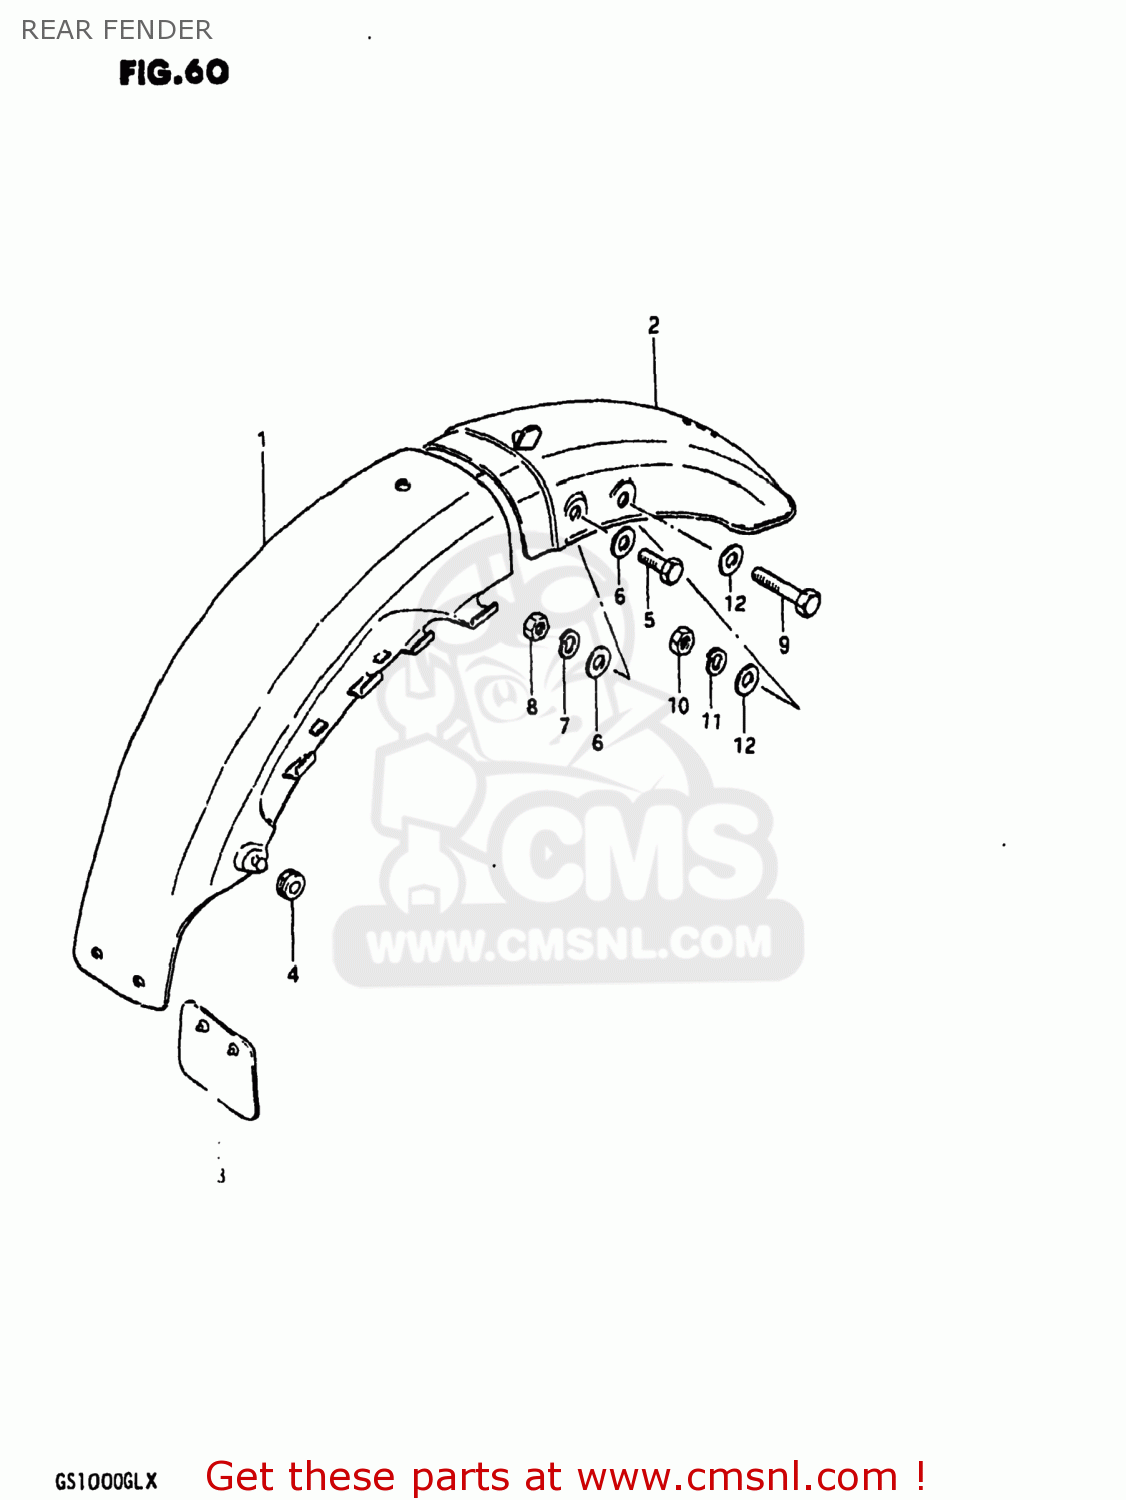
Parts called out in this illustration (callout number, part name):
1	FENDER,REAR
2	FENDER,REAR
3	GUIDE,RR FENDER MUD
4	CUSHION
5	BOLT
6	WASHER
7	LOCK WASHER
8	NUT
9	BOLT
10	NUT 8MM
11	LOCK WASHER
12	WASHER
